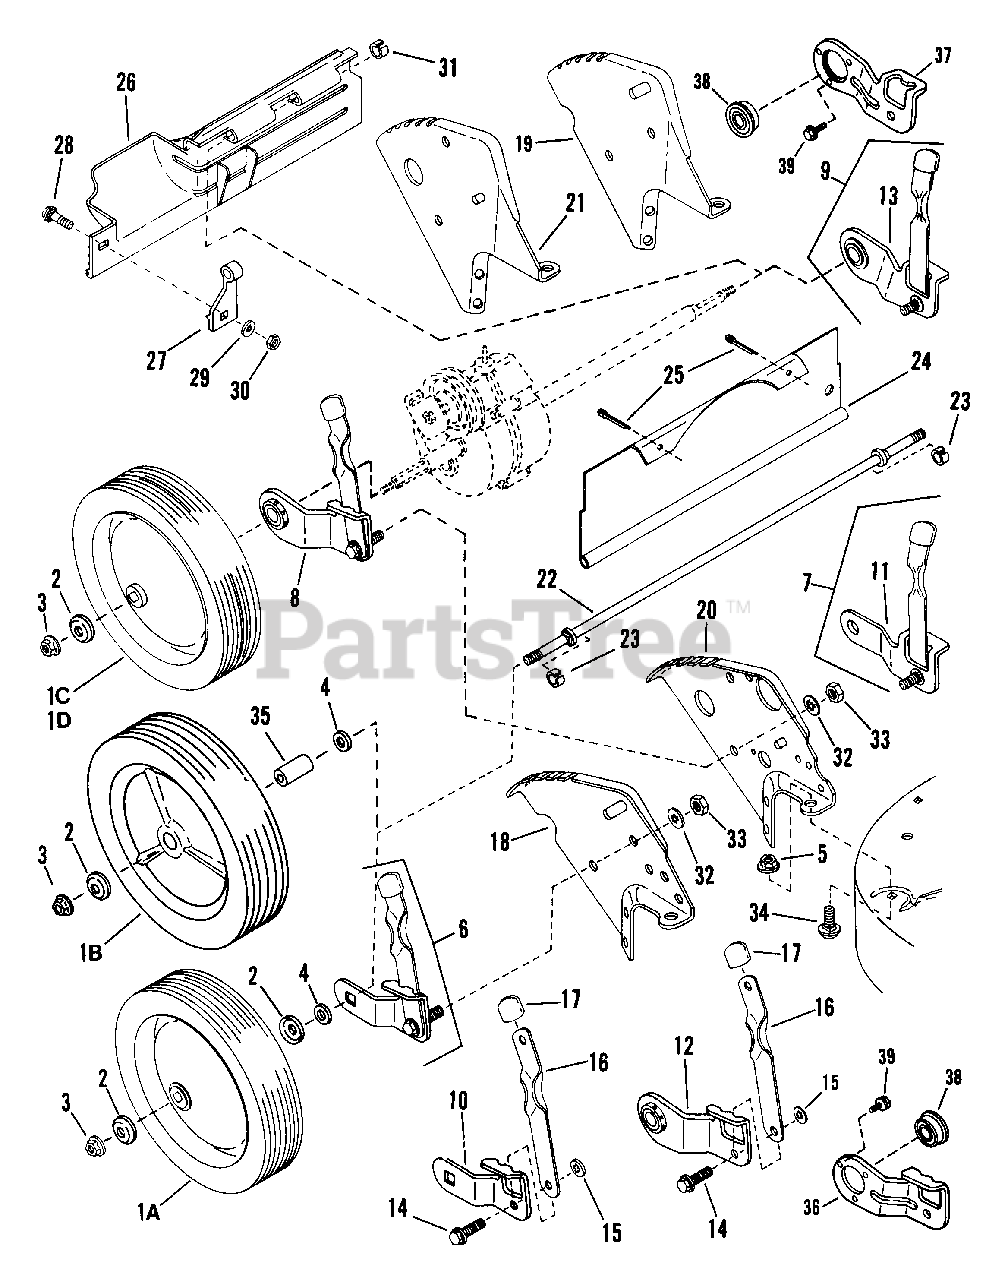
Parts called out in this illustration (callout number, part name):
1A	WHEEL, 9 x 1.75 Steel Rim (214 x 1 & 21R x 1 Push Models)
1B	WHEEL, 9 x 1.95 Steel Rim (214 x 1P4 & 21R x 1P Self Propelled Models)
1C	Wheel, 9 x 1.75 Plastic Rim (Push Models)
1D	WHEEL, 9 x 1.75 Steel Rim (Self-Propelled Models)
1E	WHEEL, 9 x 1.75 Plastic Rim (21355P Self-Propelled)
2	HUB-CAP, Deep Dish
3	NUT, 7/16-20 Hex Center Lock
4	WASHER, Steel
5	NUT, 5/16-18 Hex Flang Lock
6	WHEEL ARM ASSEMBLY (Front Left & Rear Right) Square opening
7	WHEEL ARM ASSEMBLY (Front Right & Rear Left) Round opening
8	ASSEMBLY, Wheel Arm (Rear Right "P" Models)
9	ASSEMBLY, Wheel Arm (Rear Left "P" Models)
10	ARM (Square Axle End)
11	ARM (Round Axle End)
12	ARM & BEARING ASSEMBLY, Rear Right "P" Models
13	ARM & BEARING ASSEMBLY, Rear Left "P" Models
14	BOLT, 5/16-18 x 1 Shoulder
15	RETAINER, 5/16 Bolt
16	LATCH, Height Adjusting
17	GRIP, Latch
18	BRACKET, Right Rear Wheel (Push Models)
19	BRACKET, Left Rear Wheel (Push Models)
20	BRACKET, Right Rear Wheel (Self-prop. "P" Models)
21	BRACKET, Left Rear Wheel (Self-prop. "P" Models)
22	AXLE, (Rear on Push Models also front on all)
23	RING (Push Models)
24	GUARD, Rear Foot
24	GUARD, Rear Foot (Push Models) (Plastic) ('89 Models & Later)
25	COTTER PIN, 1/8 x 1-1/2 (Steel)('88 Models & Earlier)
26	GUARD, Rear Foot (Self-prop. "P" Models)
27	SUPPORT, Foot Guard
28	BOLT, 1/4-20 x 1/2 Short Neck Carriage Gr.5
29	WASHER, 1/4 Int. Tooth Lock
30	NUT, 1/4-20 Hex
31	RING
32	WASHER, 5/16 Int. Tooth Lock
33	NUT, 5/16-18 Hex
34	BOLT, 5/16-18 x 1/2 Short Neck Carriage
35	BUSHING, Axle (Used within 1A & 1C)
36	ARM, Wheel Rear Right "P" Models ('89 Models & Later)
37	ARM, Wheel Rear Left "P" Models ('89 Models & Later)
38	BEARING
39	SCREW, #10-32 x 1/4 Self-Tapping (3)
